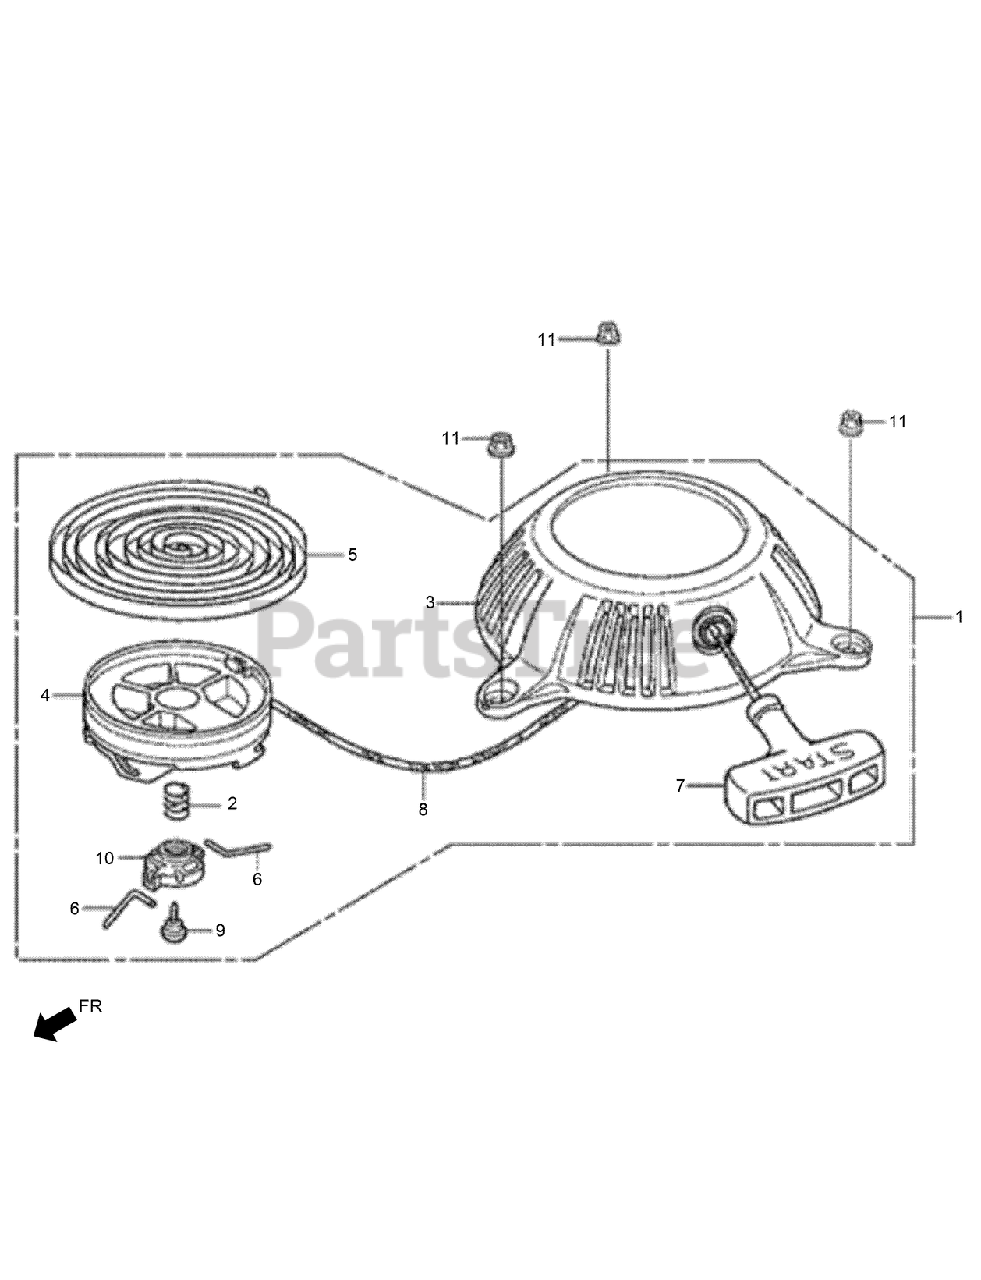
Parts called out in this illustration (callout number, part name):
1	STARTER ASM-RECOIL
2	SPRING-FRICTION
3	STARTER CASE ASM
4	REEL-RECOIL STARTER
5	SPRING-RECOIL STARTER
6	ARM-SWING
7	KNOB-RECOIL STARTER
8	ROPE-RECOIL STARTER
9	SCREW-SETTING
10	COLLAR
11	NUT-FLANGE-5MM
